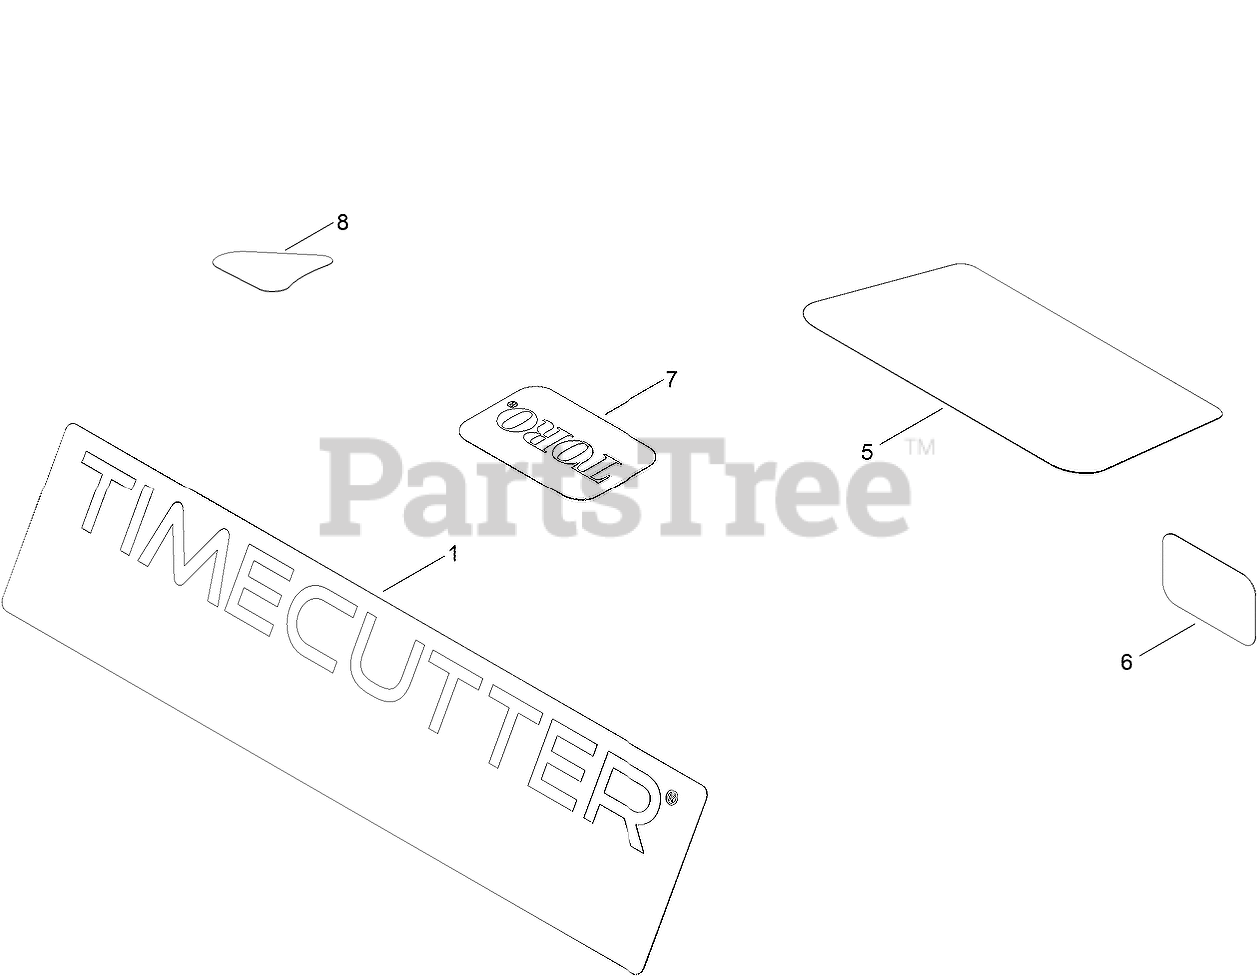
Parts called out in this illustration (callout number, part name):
1	DECAL-TIMECUTTER
5	DECAL-ENGINE
6	PLACARD-INTAKE
8	DECAL-DRAIN, OIL
